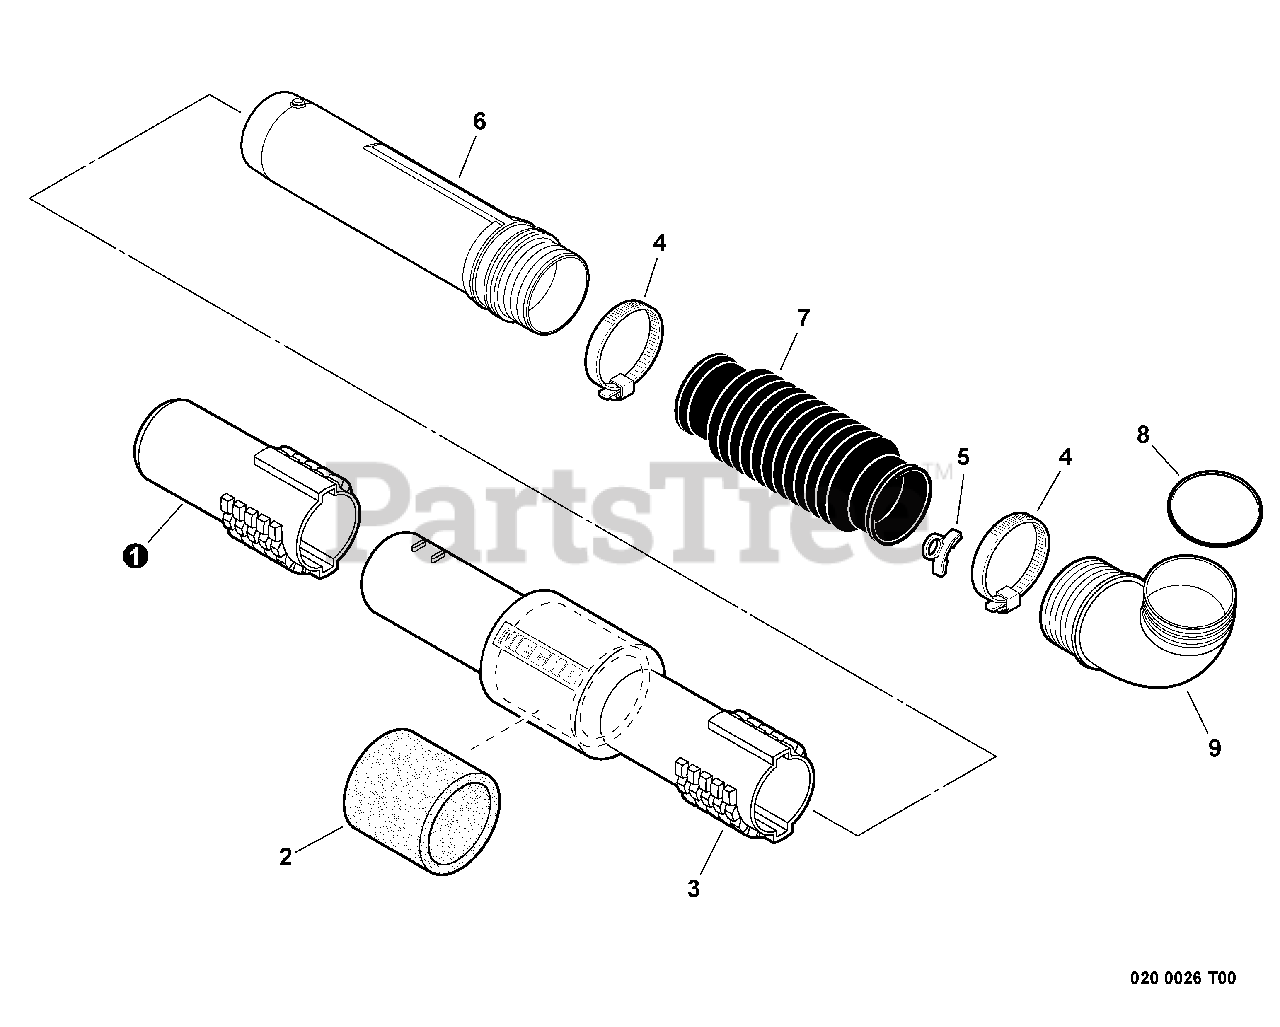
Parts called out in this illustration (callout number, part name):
1	TUBE, BLOWER - NOZZLE
2	PAD, FOAM
3	TUBE, BLOWER - STRAIGHT
4	CLAMP - BAND
5	CLIP, CABLE
6	TUBE, BLOWER - SWIVEL
7	TUBE, BLOWER - FLEXIBLE
9	TUBE, BLOWER - ELBOW
